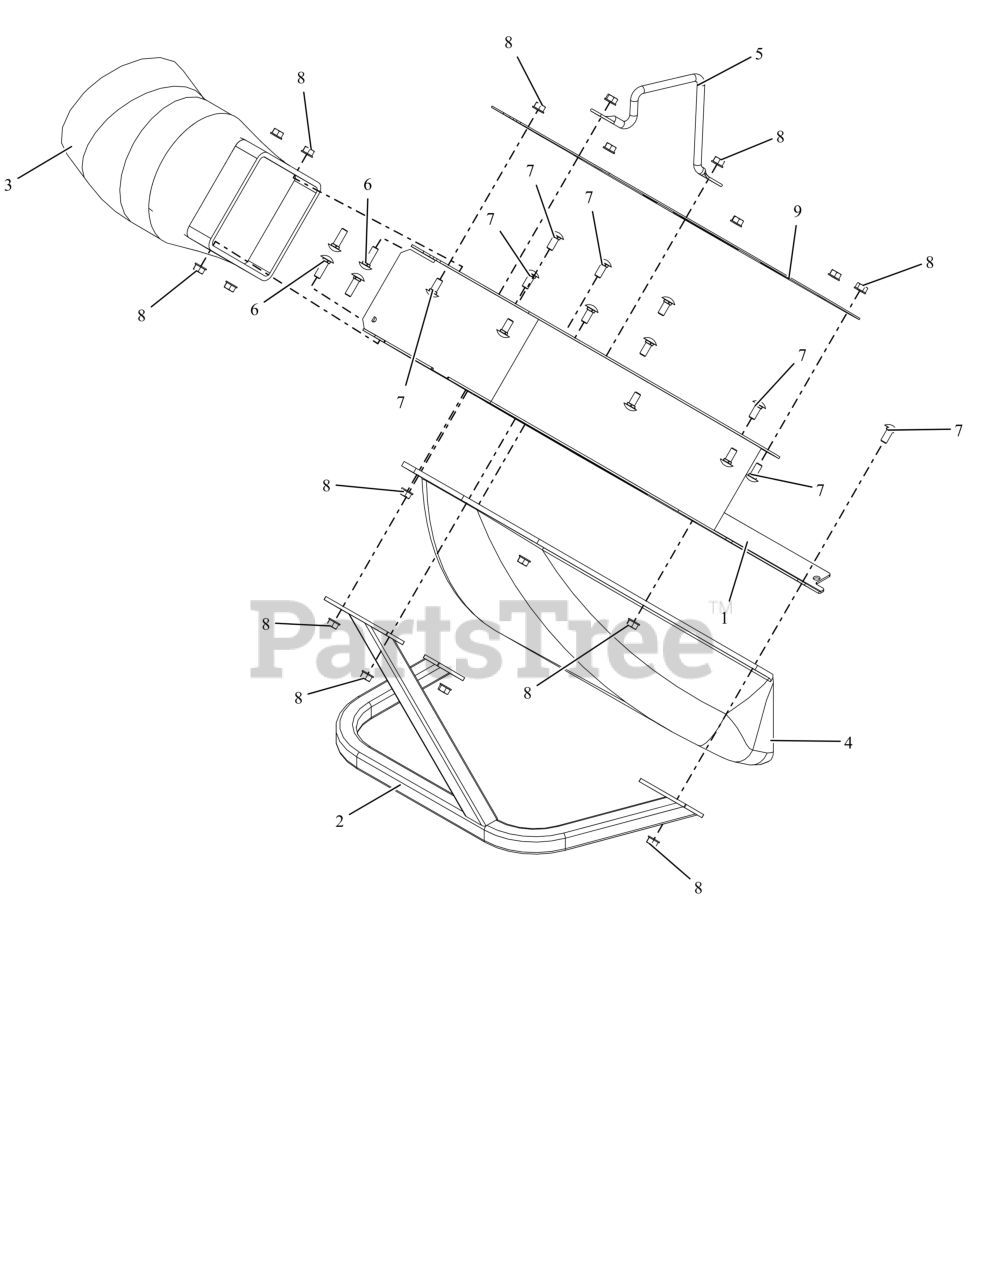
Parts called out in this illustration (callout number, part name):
1	WLDMT, HOUSING SCROLL (BLACK)
2	WLDMT, BLOWER GUARD (BLACK)
3	ADAPTER, HOSE
4	PLENUM, GRASS PUMP
5	HANDLE, BOLT-ON
6	BLT,RHSSN .31-18X1.00 G5 ZCC
7	BLT, RHSSN.31-18X.750 G5 ZCC
8	NUT-LK-TOP-FLG .312-18 GF ZCC
9	PLT, BLOWER COVER (BLACK)
